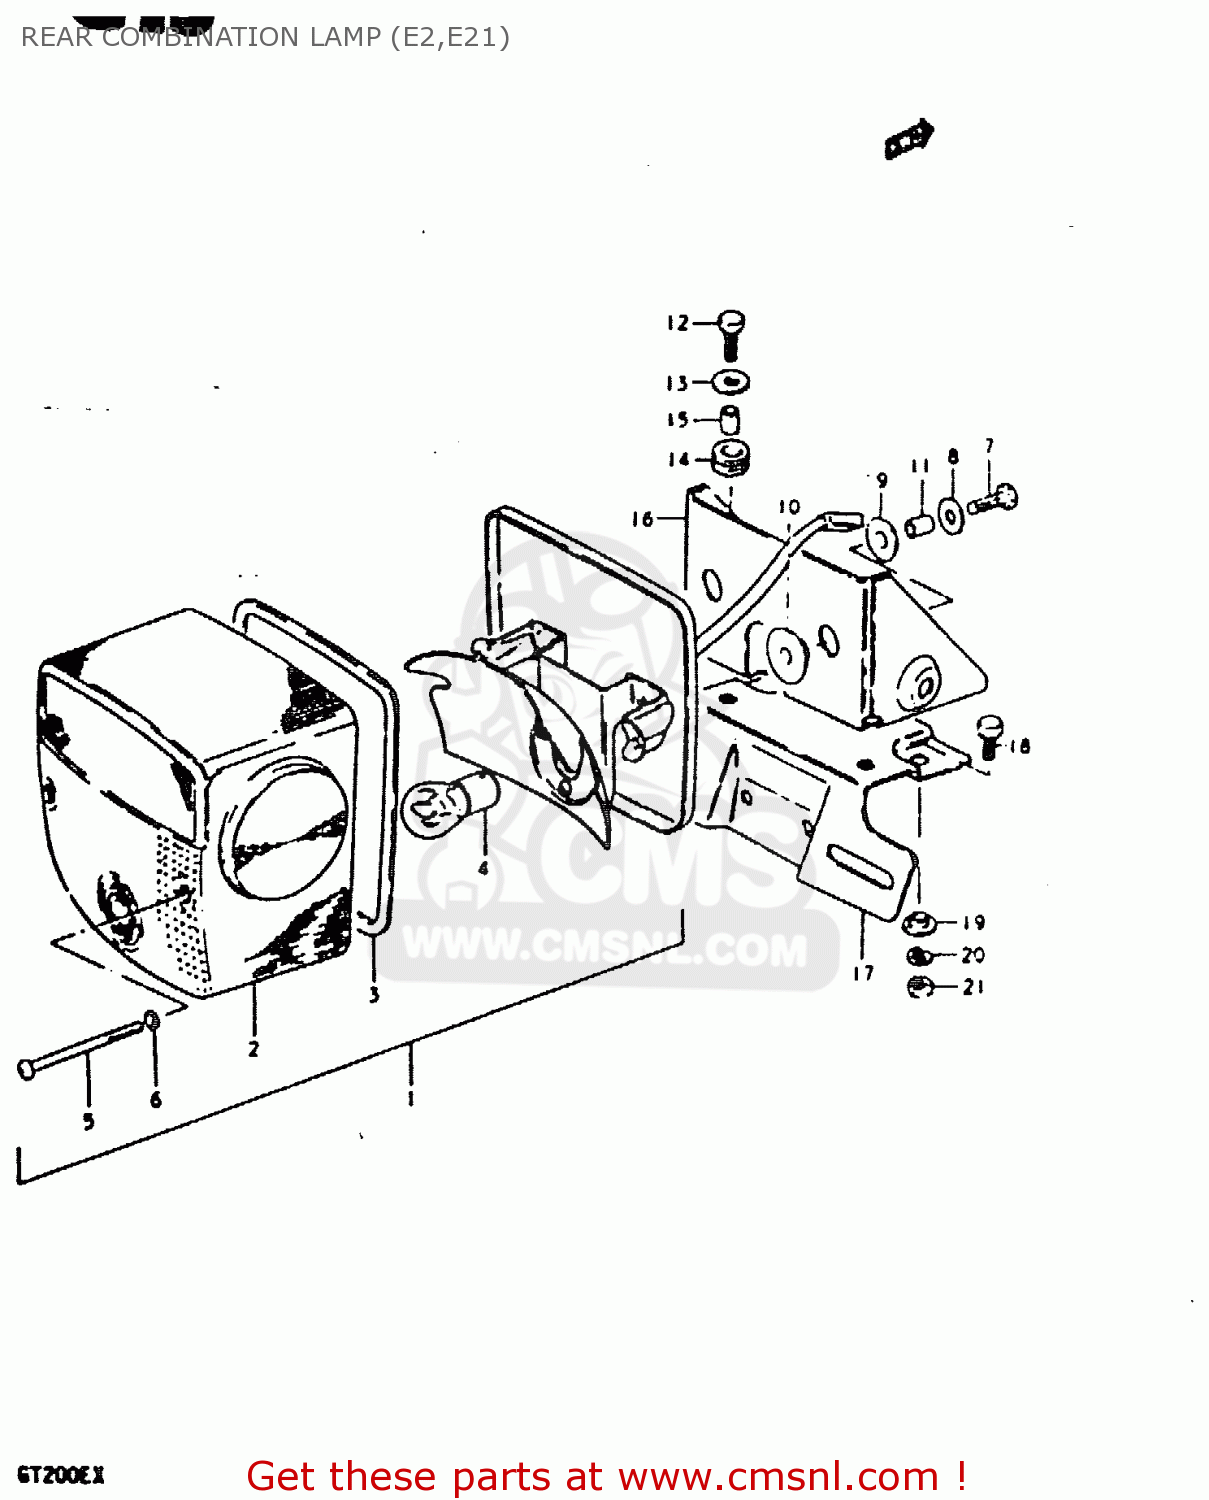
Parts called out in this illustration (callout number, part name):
1	LAMP ASSY, REAR COMBINATION
2	LENS
3	GASKET (NAS)
4	BULB 12V21/5W
5	SCREW (4X55)
6	GASKET (NAS)
7	BOLT
8	WASHER (6.5X20X1.2)
9	CUSHION
10	CUSHION
11	SPACER (6.8X10X11.5)
12	BOLT, UPPER
13	WASHER (6.5X20X1.2)
14	CUSHION
15	SPACER (6.1X9X9)
16	BRACKET, COMBINATION LAMP
17	PLATE, LICENSE
18	BOLT
19	SPACER
20	LOCK WASHER
21	NUT
